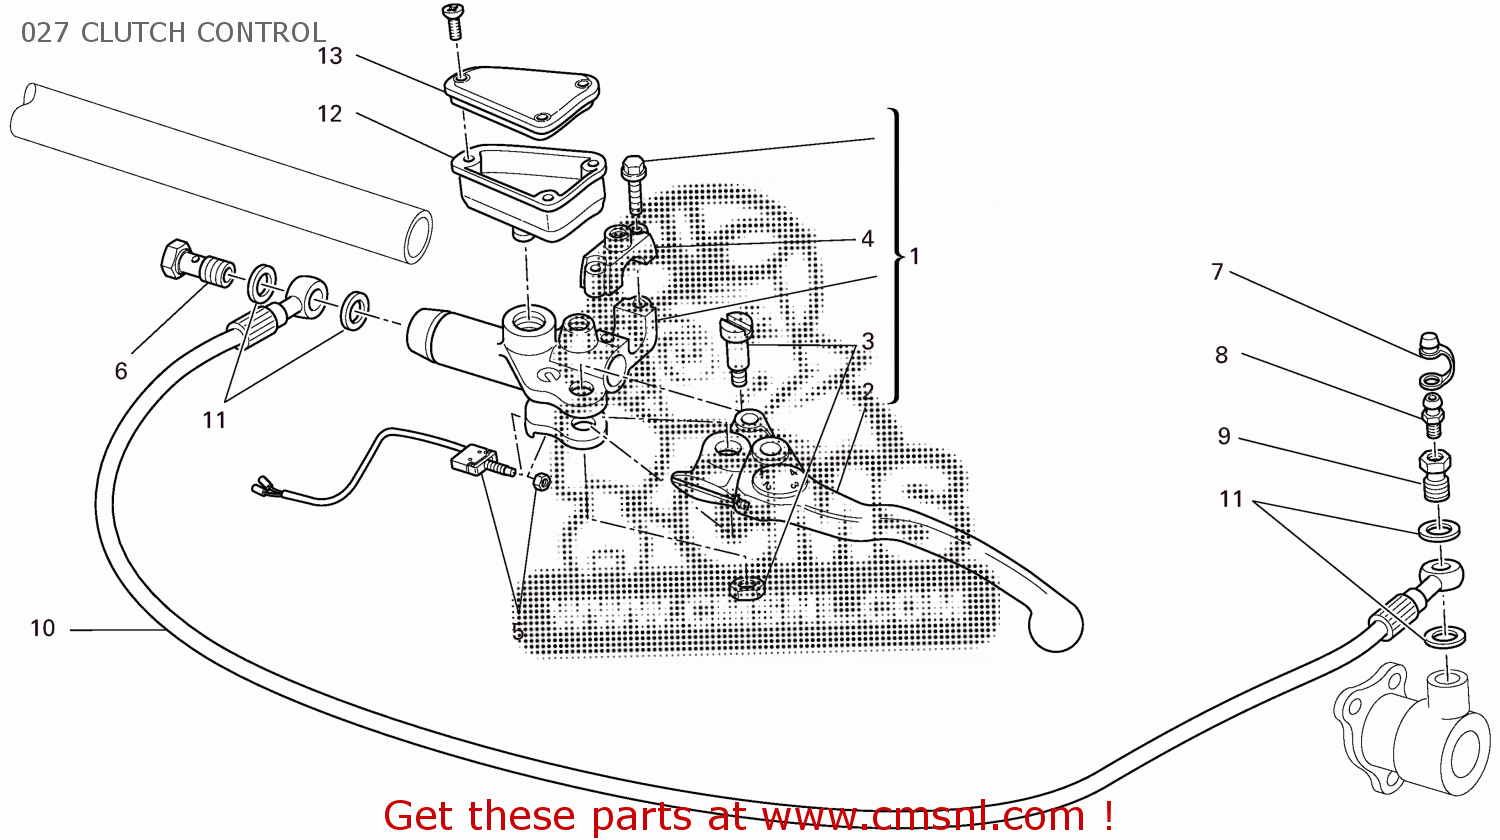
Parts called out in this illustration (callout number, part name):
1	CLUTCH MASTER CYLINDER
2	CLUTCH LEVER
3	BOLT, PIVOT
4	BRACKET, CLUTCH MASTER CYLINDER
5	SWITCH, CLUTCH
6	BOLT, BRAKE HOSE M10X1
7	DUST COVER
8	VALVE, BREATHER
9	BOLT, BRAKE HOSE
10	CLUTCH OIL HOSE
11	COPPER GASKET 11.9X8.2X2
12	SUB TANK, OIL
13	CLUTCH BRAKE PUMP COVER KIT
